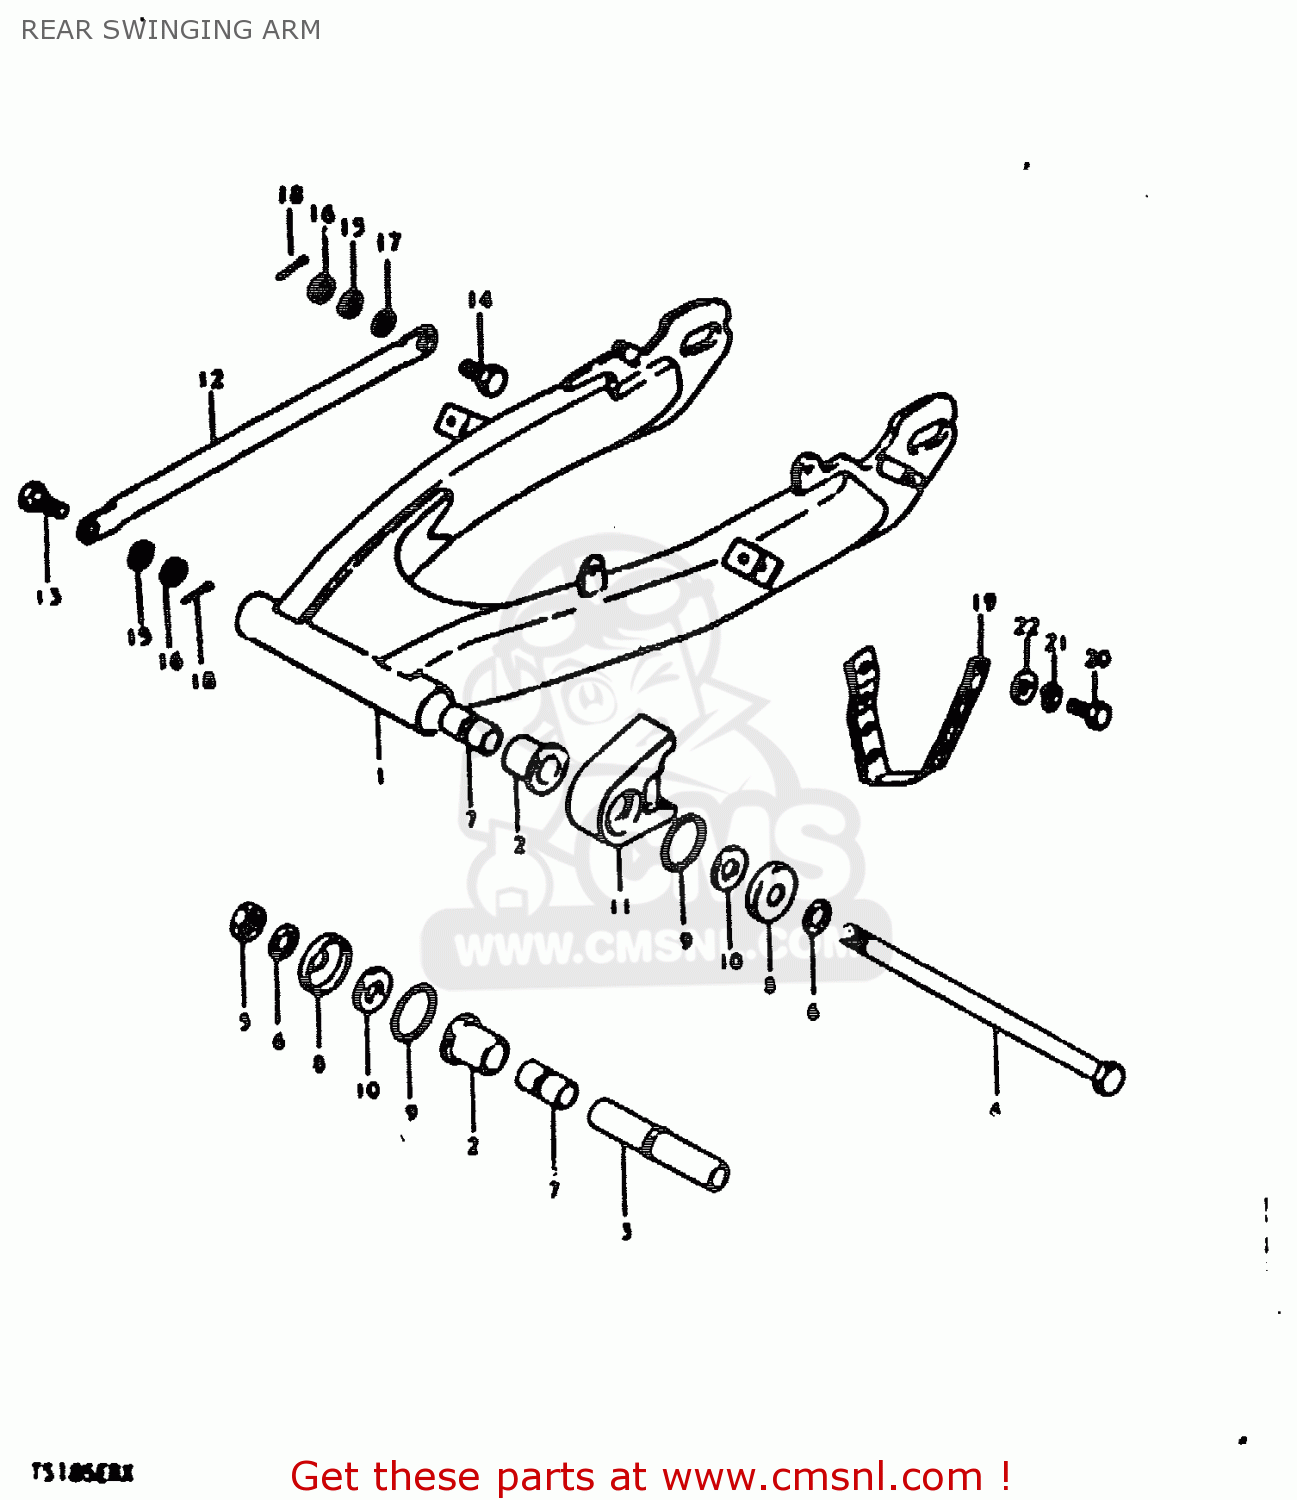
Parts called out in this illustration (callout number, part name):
1	ARM,REAR SWING
2	BUSH
3	SPACER,RR SWGARM PIVOT CTR
4	SHAFT,REAR SWING ARM
5	NUT 12MM
6	WASHER
7	SPACER
8	COVER,SWGARM BUSH DUST SEAL
9	DUST SEAL
10	WASHER(12.5X24X2.3)
11	BUFFER,CHAIN TOUCH DEFENSE
12	TORQUE LINK,REAR
13	BOLT(8X22)
14	BOLT(8X26.5)
15	LOCK WASHER
16	NUT
17	WASHER
18	PIN
19	GUIDE,CHAIN
20	BOLT 8X12
21	LOCK WASHER
22	WASHER
